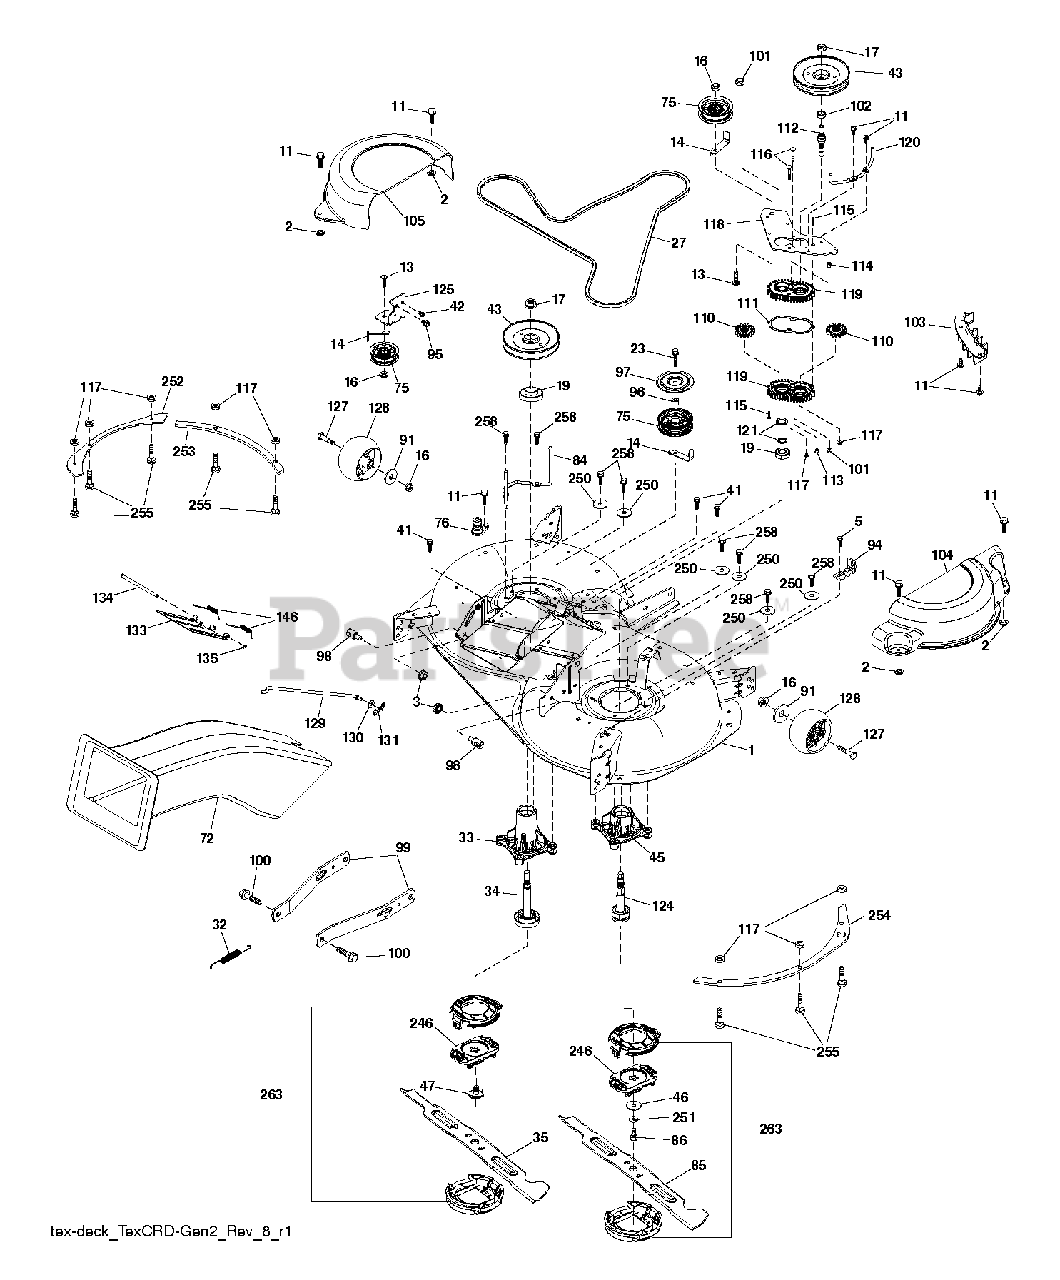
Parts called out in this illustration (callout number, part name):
1	DECK.SVC.WLDT.97EL.TCRD.EZ.498
2	PALNUT 1/4
3	NUT LOCK HEX FLANGE 5/16-18
5	BOLT.5/16HEX.WHS.HD
11	SCREW.1/4-20X5/8
13	BOLT.3/8-16X1.50
14	KEEPER, BELT IDLER
16	NUT LOCK FLG 3/8-16 UNC
17	NUT.FLANGE.LOCK.TOP
19	BEARING.MANDREL.TOP.EXTENDED
23	SCREW LT
27	BELT 97CM ELECTRIC
32	SPRING 107CM & 97CM ELECTRIC D
33	HOUSING.MANDREL.REV.TALL.N/GRS
34	SHAFT ASM.REV.TALL.N/GREASEBL
35	BLADE.REVOLUTION.97CM.LHS
41	BOLT.HEX.WASHR.HED.313-18X1.19
42	SCREW
43	PULLEY.MANDREL.5.0.PD.38"
45	RP HOUSING.MANDREL.REV.REVS.
46	3/8 FLAT WASHER
47	SCREW.SEMS.7/16-20X1.HEX.HEAD
72	RB CHUTE 107/97 TEX GENII
75	FLAT IDLER PULLEY
76	PORT.WASHOUT
84	BELT KEEPER.MANDREL.38"COATED
85	BLADE.REVOLUTION.97CM.RHS
86	BOLT.3/8-24X1.25GR8. LHTHRD
91	WASHER
94	BRKT.CLUTCH.CABLE
95	SCREW, 3/8-16X3/4
96	SPACER
97	PROTECTOR
98	STUD.FASTNER.W/ANTI-ROTATE
99	ARM.SUSPENSION.MOWER.R
100	BOLT.SHOULDER
101	NUT.CROWNLOCK.9/16 -18.UNC
102	SPACER BEARING
103	GUARD GUARD FRONT VENT
104	97.CRD.RH.MANDREL.COVER
105	MANDREL MANDREL COVER LH
110	CRD.SPUR.GEAR
111	GASKET GASKET GEARCASE
112	SHAFT SHAFT. CRD GEARCASE ADAP
113	PLUG PLUG OIL
114	VENT.BREATHER.1/8 NPT
115	SCREW
116	BOLT.CARIGE.SS.1/4-20X1.75GR5
117	NUT T
118	ARM ARM CLUTCHING
119	GEARCASE GEARCASE SUBASM
120	BRACKET KEEPER BELT RH
121	WASHER WASHER
124	SUB.ASM.REVERSE.THREAD.REV
125	BRACKET
127	BOLT.SHOULDER.3/8-16X3-5/8.
128	WHEEL. GUAGE RALLY
129	ROD ROD. SWAY CRD GEN II
130	WASHER
131	PIN.COTTER.5/16.BOW TI
133	DOOR
134	PIN PIN.HINGE
135	E-RING.5/16"
146	SPRING SPRING: EZ MULCH DOOR
246	HOLDER.BLADE.REVOLUTION
251	LOCKWASHER
252	PLATE.REINFORCEMENT.X431
253	PLATE.REINFORCEMENT.LHS.X431
254	PLATE.REINFORCEMENT.LHS.X431
255	RHSNB, 1/4-20 X 1, GR5
258	BOLT.HEX.WASHR.HED.313-18X1.19
263	CAP.REVOLUTION ASM
